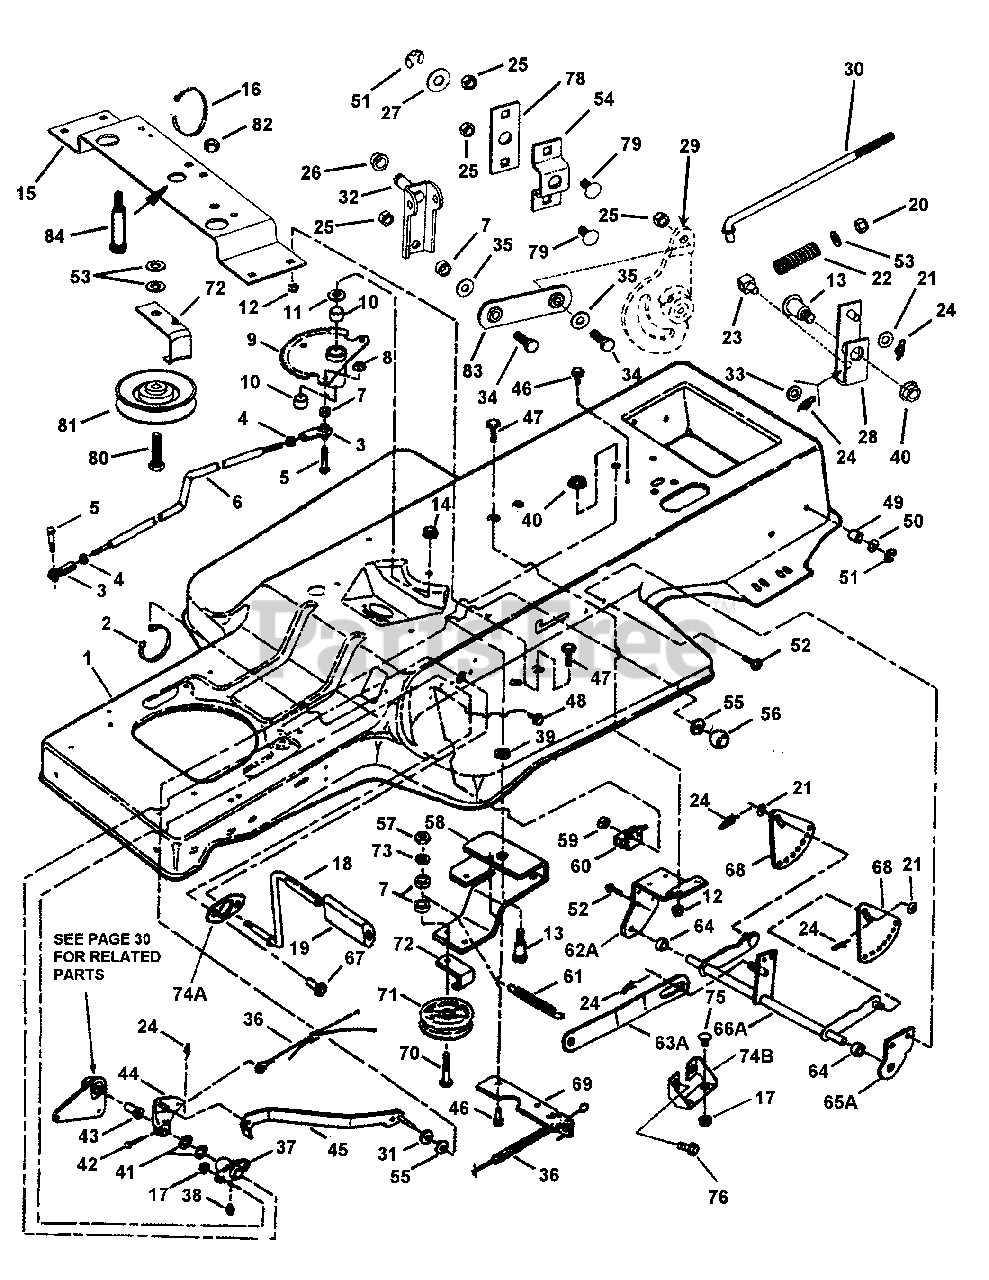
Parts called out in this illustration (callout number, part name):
1	FRAME, Tractor (1 piece)
2	TIE, Wire
3	BALL JOINT, 3/8-24
4	NUT, 3/8-24 Hex Jam
5	SCREW, 3/8-24 x 1-1/4" HHC
6	LINK, Drag
7	SPACER
8	NUT, 3/8-16 Hex Flange Lock
9	ASS'Y, Sector Gear
10	BEARING, Sector Gear
11	WASHER, 3/4" Thrust
12	NUT, 1/4-20 Hex Flange Lock
13	BOLT, 1/2-13 x 2" Shoulder
14	NUT, 1/2-13 Hex Ctr. Lock, Gr. A
15	BRACE, Sector Gear
16	TIE, Cable 7"
17	NUT, 5/16-18 Hx, Flg. Lk., Gr 5
18	PEDAL, Clutch Brake
19	PAD, Pedal
20	NUT, 3/8-16 Hex Nyloc
21	WASHER, 3/8 Bright Zinc, Flat
22	SPRING, Brake
23	SWIVEL, Inline Brake
24	PIN, 3/8 x 1-7/32" Cotter (Self-Locking)
25	NUT, 5/16-18 Hex Center Lock
26	BUSHING, 7/16" I.D.
27	WASHER, .44" I.D. Flat
28	WELDMENT, Brake Arm
29	ARM, Speed Control
30	ROD, Brake
31	WASHER, 5/16" Flat
32	WELDMENT, Pivot Shift Lever
33	WASHER, .406 I.D. Flat
34	SCREW, 5/16-18 x 1-1/4" Grade 5
35	WASHER, 5/16" Flat
36	ASSEMBLY, Clutch/Brake Cable
37	ASSEMBLY, Foot Shaft Pivot
38	LUBE FITTING, Straight (press-fit for .187 dia. Hole)
39	WASHER, 1/2" Internal Tooth Lock
40	NUT, 1/2-13 Hex Flange Lock
41	WASHER, 5/8" Flat
42	PIN, 3/16 x 1-1/2" Clevis
43	BEARING, Flange
44	WELDMENT, Clutch Brake Arm
45	LATCH, Park Brake
46	SCREW, 5/16-18 x 5/8" S. Tap
47	BOLT, 1/4-20 x 5/8" Carriage
48	SCREW, #10-32 x 5/8" H.W.H.
49	BUSHING, 1/2" Nylon
50	WASHER, 1/2" Flat
51	RING, 1/2" External Retaining
52	SCREW, 5/16-18 x 5/8" Truss
53	WASHER, 3/8" Flat
54	BRACKET, Pivot Mounting
55	WASHER, 5/16" Nylon
56	KNOB, Clutch/Brake (5/16-18)
57	NUT, 3/8-16 Hex, Grade B or 5
58	ARM, Idler (Traction Drive)
59	NUT, #10-32 Hex Nyloc
60	SWITCH, DPDT NC/NO
61	SPRING, Traction Drive
62A	BRACKET, Rear Lift/PTO Lever
63A	LINK, Lift
65A	BRACKET, Deck Hang Pivot
66A	WELDMENT, Rear Lift
67	SCREW, 5/16-18 x 7/8" Truss Head (Torx)
68	PLATE, Lift Sector
69	EXTENSION, Idler Arm
70	SCREW, 3/8-16 x 2-1/4" Cap Grade 5
71	PULLEY, Flat Idler, 3.47" O.D.
72	GUIDE, Pulley
73	WASHER, 3/8" Split Lock
74A	WASHER, Pivot, Stiffener
74B	BRACKET, Frame Brace
75	BOLT, 5/16-18 x 5/8" Short Neck Carriage, Grade 5
76	SCREW, 5/16-18 x 3/4" HWST
78	BRACKET, Mounting Brace
79	BOLT, 5/16-18 x 3/4" Carriage,
80	SCREW, 3/8-16 x 1-1/2" Cap, Grade 5
81	PULLEY, Idler V 3.30 HA
82	NUT, 3/8-16 Hex Center Lock
83	LINK, Fwd/Rev
84	BOLT, 1/2-13x3-7/8" Shoulder
